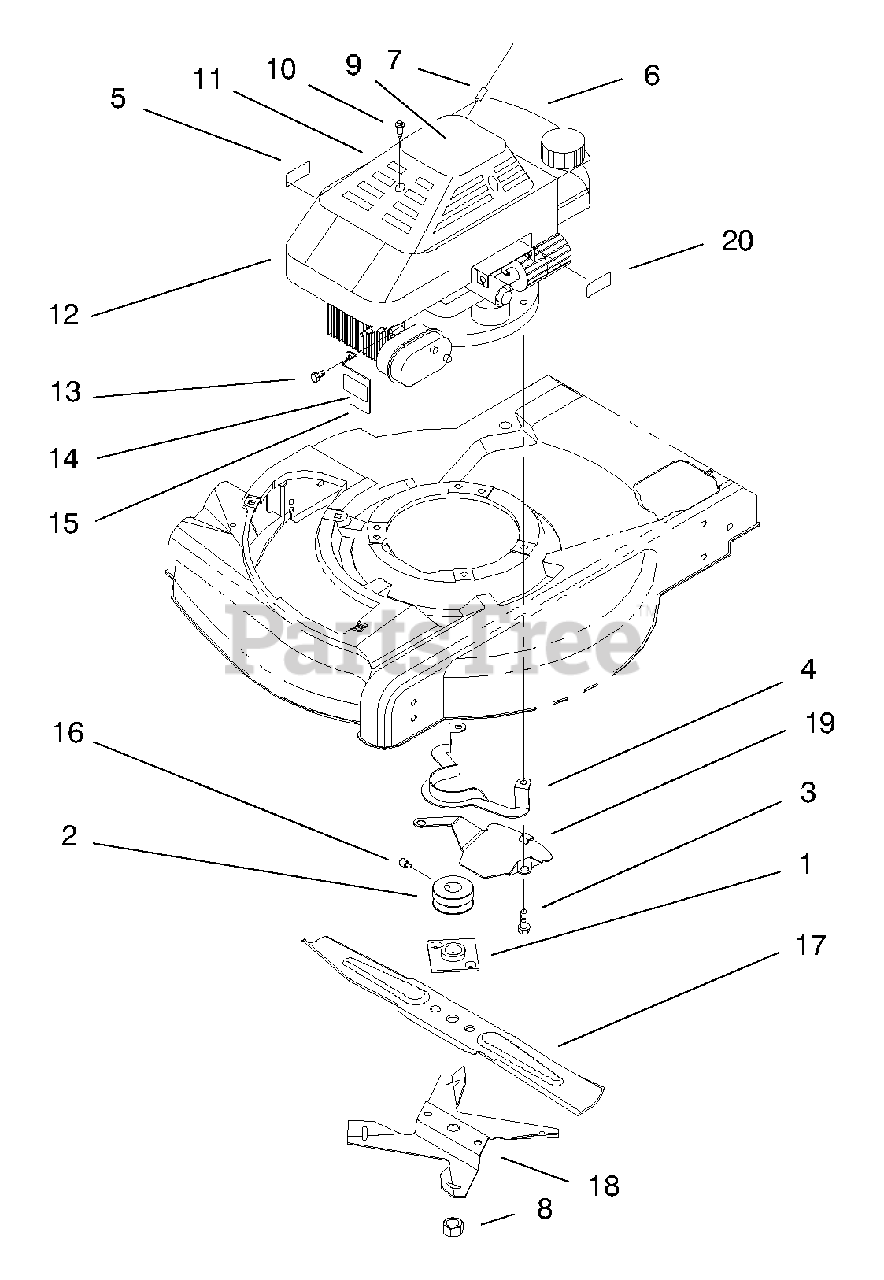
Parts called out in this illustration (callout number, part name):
1	ASM-Plate & Collar
2	Pulley-Engine
3	Screw-Engine Mount
4	Guide-Belt
5	Decal-Oil Instruction
6	ASM-Engine
7	Rope-Stop
8	Nut-Blade
9	Decal-Shroud
10	Screw-Recoil Cover
11	Cover-Starter
12	Shroud-Engine
14	Decal-Hot Surface
15	Guard-Muffler
16	Screw-Set
17	Blade-21" Whirl
18	Fan-Mulching
19	Shield-Grass
20	Decal-Primer
